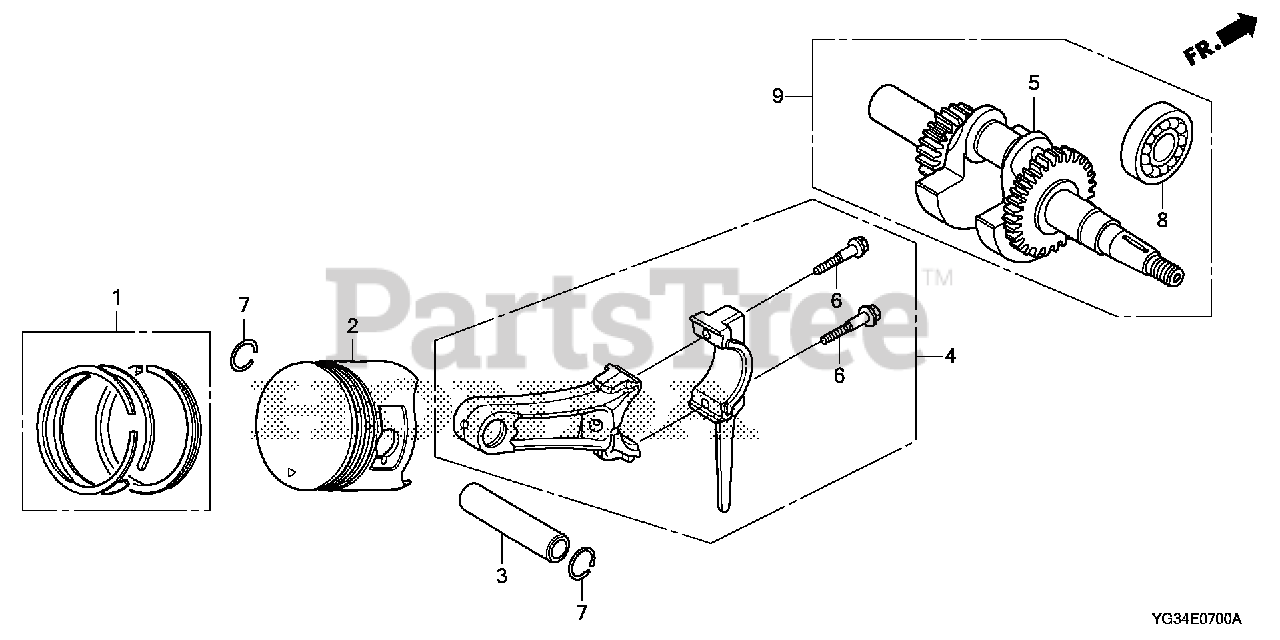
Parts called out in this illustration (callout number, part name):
1	RING SET, PISTON (0.25) Use from Engine SN 1314913.
1	RING SET, PISTON (0.25) (RIKEN)
1	RING SET, PISTON (0.50) (TPR)
1	RING SET, PISTON (0.50) (RIKEN)
1	RING SET, PISTON (STD) (RIKEN)
2	PISTON (STD)
2	PISTON (0.25)
2	PISTON (0.50)
3	PIN, PISTON
4	ROD ASSY., CONNECTING (UNDER SIZE)
4	ROD ASSY., CONNECTING
5	CRANKSHAFT
6	BOLT, CONNECTING ROD (6X34.5)
7	CLIP, PISTON PIN (18MM)
